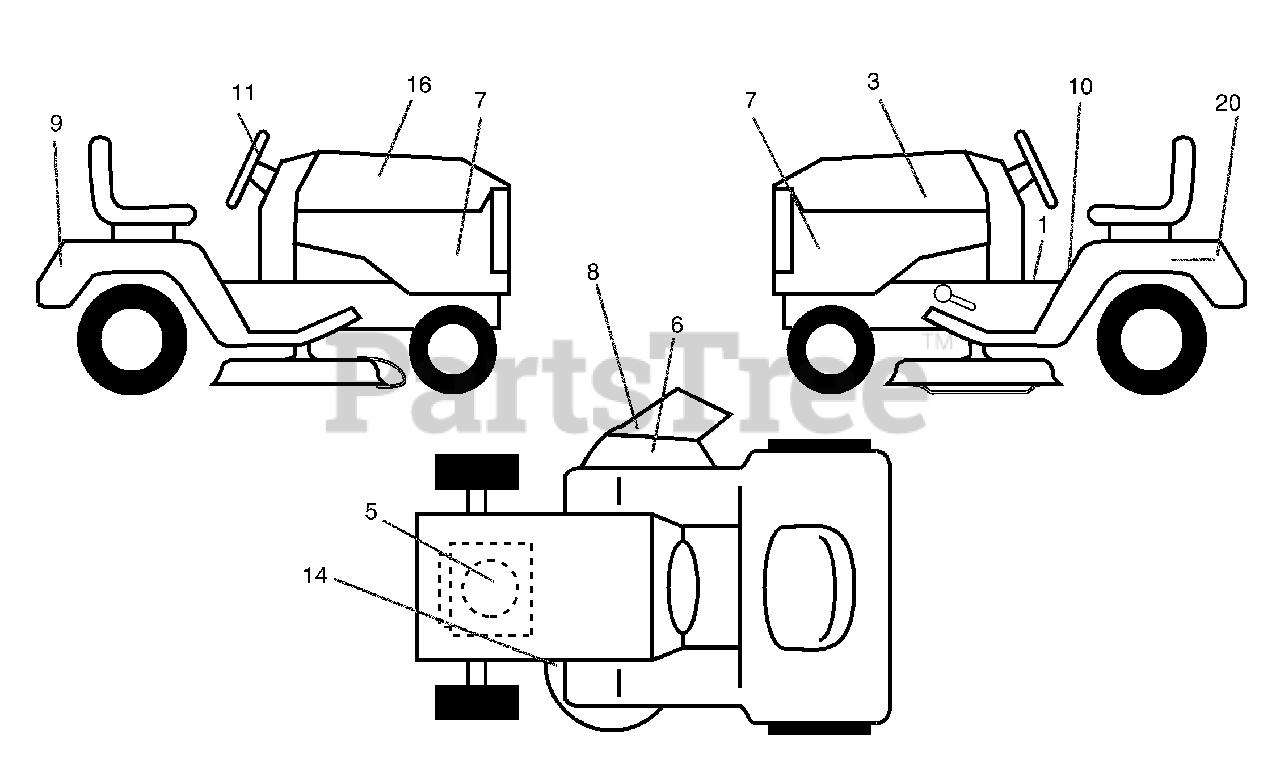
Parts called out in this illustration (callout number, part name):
3	Decal Hood LH
4	Decal Replace
5	Decal HP Engine
6	Decal Deck "B" 42"
7	Decal Side Panel
8	Decal Warning Mult-Language
9	Decal Fender Logo
10	Decal Fender Danger E/F
11	Decal Ins Strg Whl
14	Decal V-Belt Schematic
16	Decal Hood Rh
20	Decal Bat Dan/Psn
